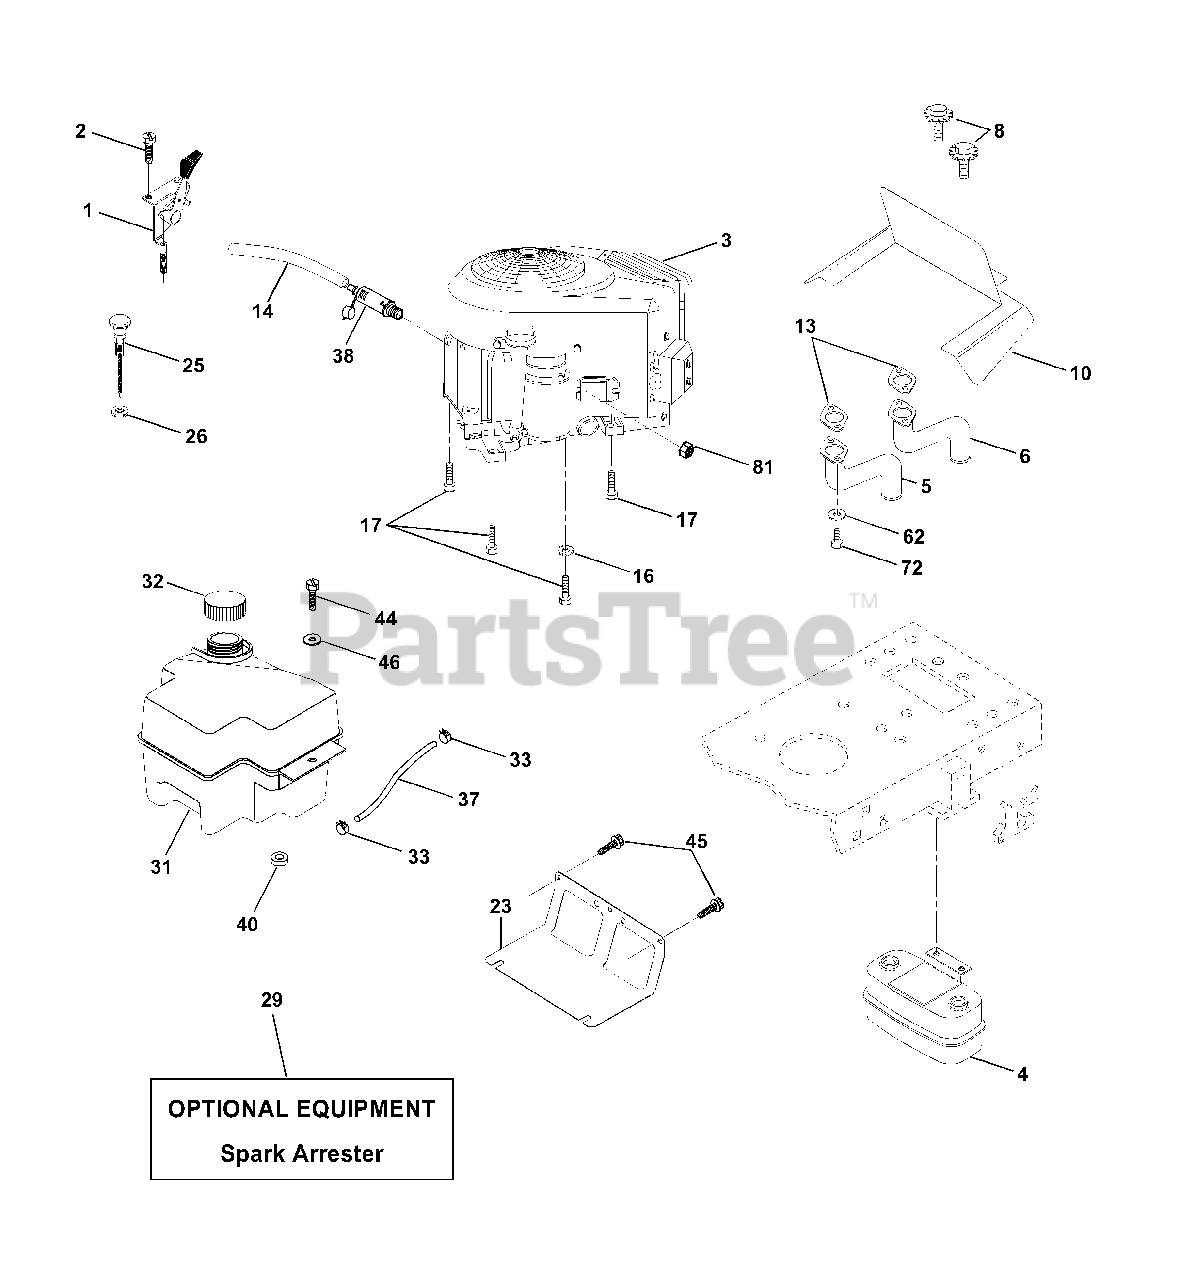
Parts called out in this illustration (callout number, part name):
1	Control, Throttle
2	Screw Hex Thd Cut 1/4-20 x 5/8
4	Muffler, Asm. Twin Lo-Tone
5	Pipe Exhaust Intek 20 RH
6	Pipe Exhaust Intek 20 LH
8	Bolt 5/16-18 UNC x 3/4 w/Sems
10	Shield Browing B&S Intek II
13	Muffler Gasket
14	Tube Drain Oil Easy
16	Washer, Lock Ext tooth 3/8
17	Screw Thdrol 3/8-16 x 1-1/2
23	Shield, Browning/Debris Guard
25	Control Choke
26	Nut Keps 3/8-24 UNF
29	Arrester, Spark
31	Tank, Fuel
32	Cap Gauge, Fuel
33	Clamp, Hose Blk
37	Line, Fuel 7.5
38	Plug Drain Oil Easy
40	Bushing Snap Nyl Blk Fuel Line
44	Screw Hex Wsh Thdrol 1/4-20 x 3/4
45	Screw Hex Wsh Thdrol 3/8-16 x 3/4
46	Washer 9/32 x 7/8 x 16 Ga.
62	Washer Lock Hvy Hlcl Spr 5/16
72	Screw Hex Hd Cap 5/16-18 x 3/4
81	Nut Keps Hex 1/4-20 Unc
